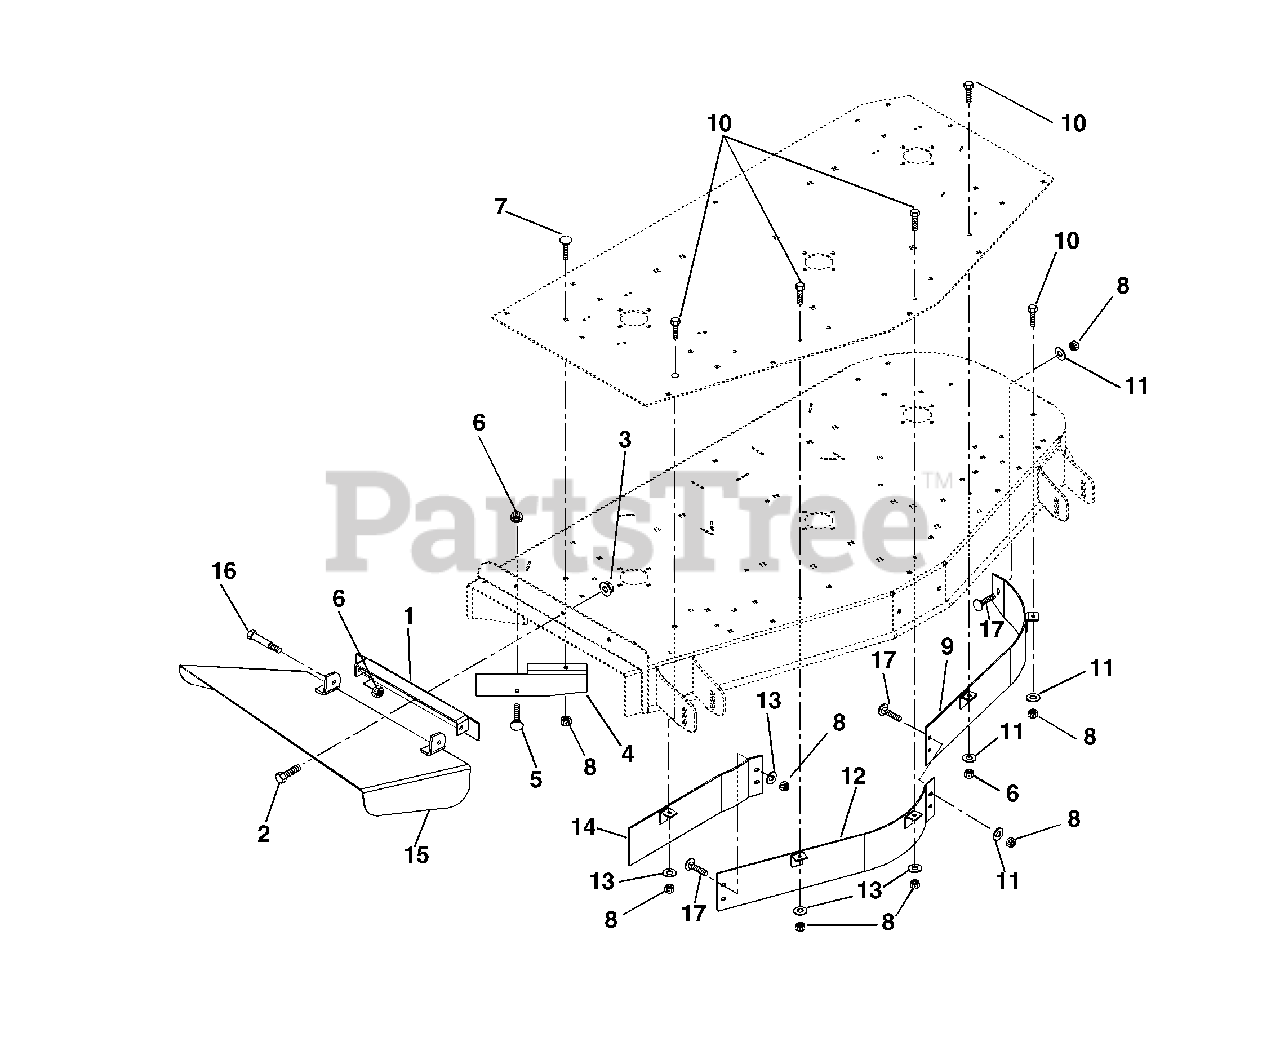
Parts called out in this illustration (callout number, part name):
1	Weldment, Discharge Chute Bracket
2	Bolt-Hex .38-16 x 1.00 Grade 5
3	Nut-Locking-Flange .38-16
4	Deflector, 72"
5	Bolt-Round Head Square Neck .38-16 x 1.00 Grade 2
6	Nut-Locking-Center .38-16
7	Bolt-Round Head Square Neck .31-18 x 1.00 Grade 5
8	Nut-Locking-Nylon .31-18
9	Weldment, 72" Left Hand Baffle
10	Bolt-Hex .31-18 x 1.00 Grade 5
11	Washer-Flat-Steel .312 x .734 x .065
12	Weldment, 72" Center Baffle
13	Washer-Flat-Steel .312 x .734 x .065
14	Weldment, 72" Right Hand Baffle
15	Weldment, Discharge Chute 72"
16	Bolt-Shoulder .38-16 x .38
17	Bolt-Round Head Square Neck .31-18 x .75 Grade 2
18	72" S.D. Mulch Kit
19	72" Discharge Cover Kit
